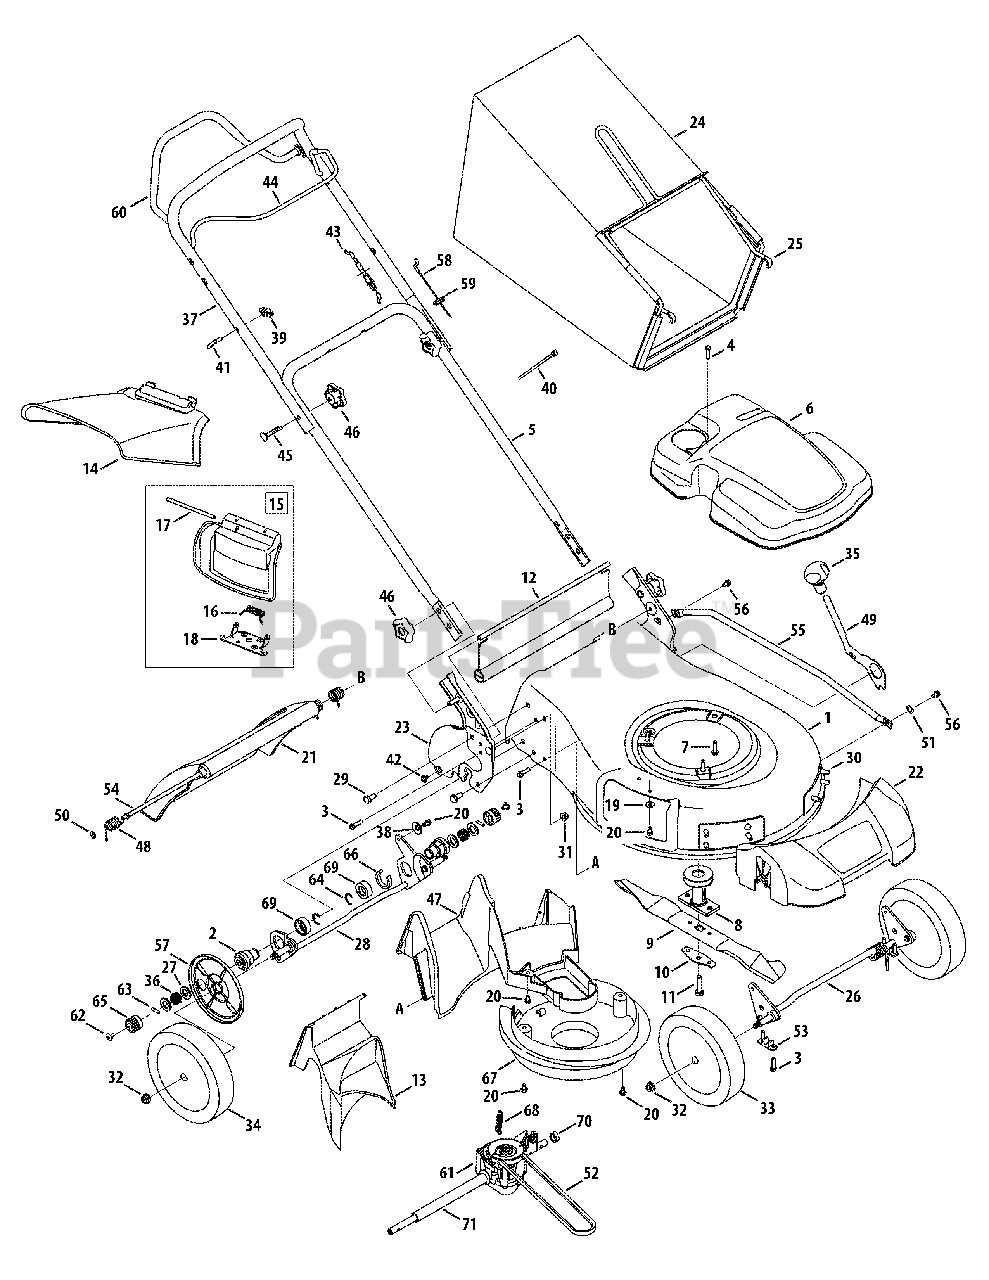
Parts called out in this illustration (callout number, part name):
2	Transmission Support Bearing
3	Screw, 1/4-15 x 1.000
4	Screw, HL, #12-16 x 1.00
5	Lower Handle
6	Engine Shroud
7	Screw, 3/8-16 x 1.00
8	Blade Adapter
9	Mulching Blade
10	Blade Bell Support
11	Screw, 3/8-24 x 1.50
12	Trailing Shield
13	Rear Mulch Plug
14	Side Discharge Chute
15	Mulch Plug (Incl. 16-18)
16	Torsion Spring
17	Hinge Pin
18	Chute Deflector Adapter
19	Belleville Washer
20	Screw
21	Rear Door
22	Front Cover
23	Handle Bracket - RH
23	Handle Bracket - LH
24	Grass Bag
25	Grass Bag Frame
26	Front Bracket Assembly
27	Washer, Flat, .508 x 1.00 x .020
28	Self Propelled Bracket Ass’y
29	Hhcs, 5/16-18 x .625
30	Screw, 5/16-14 x .750
31	Nut, Flange Lock, 5/16-18
32	Nut, Flange Lock, 3/8-16
33	Front Wheel
34	Rear Wheel
36	Wave Spring
37	Upper Handle
38	Washer, Bell, .340 x .872 x .060
40	Cable Tie
41	Rope Guide
42	Screw, #10-16 x .500
43	Control Cable
44	Blade Control
45	Bolt Carriage, 5/16-18 x 2.0
46	Star Knob
47	Rear Baffle
48	Door Torsion Spring - RH
48	Door Torsion Spring - LH
49	Spring Lever
50	Nut, Spd
51	Wshr, Wave, .385 ID x .598 OD
52	V-Belt
53	Bushing, Lock, .505 Dia. X .62
54	Rear Door Pivot Rod
55	Cross Bracket
56	Scr., Shldr., 1/4-20 x .50
57	Wheel Dust Cover
58	Drive Cable
59	Grommet
60	Drive Control
61	Transmission
62	Screw, 1/4-20 x .390
63	Dowel Pin
64	Retainer Ring
65	Spur Gear - RH
65	Spur Gear - LH
66	Spacer, Clip
67	Engine Baffle
68	Exten. Spring, .429OD x 2.515
69	Bearing Support Spacer
70	Sleeve Spacer, .550ID x .340 Lg.
71	Sleeve Spacer, .550ID x 7.97 Lg.
